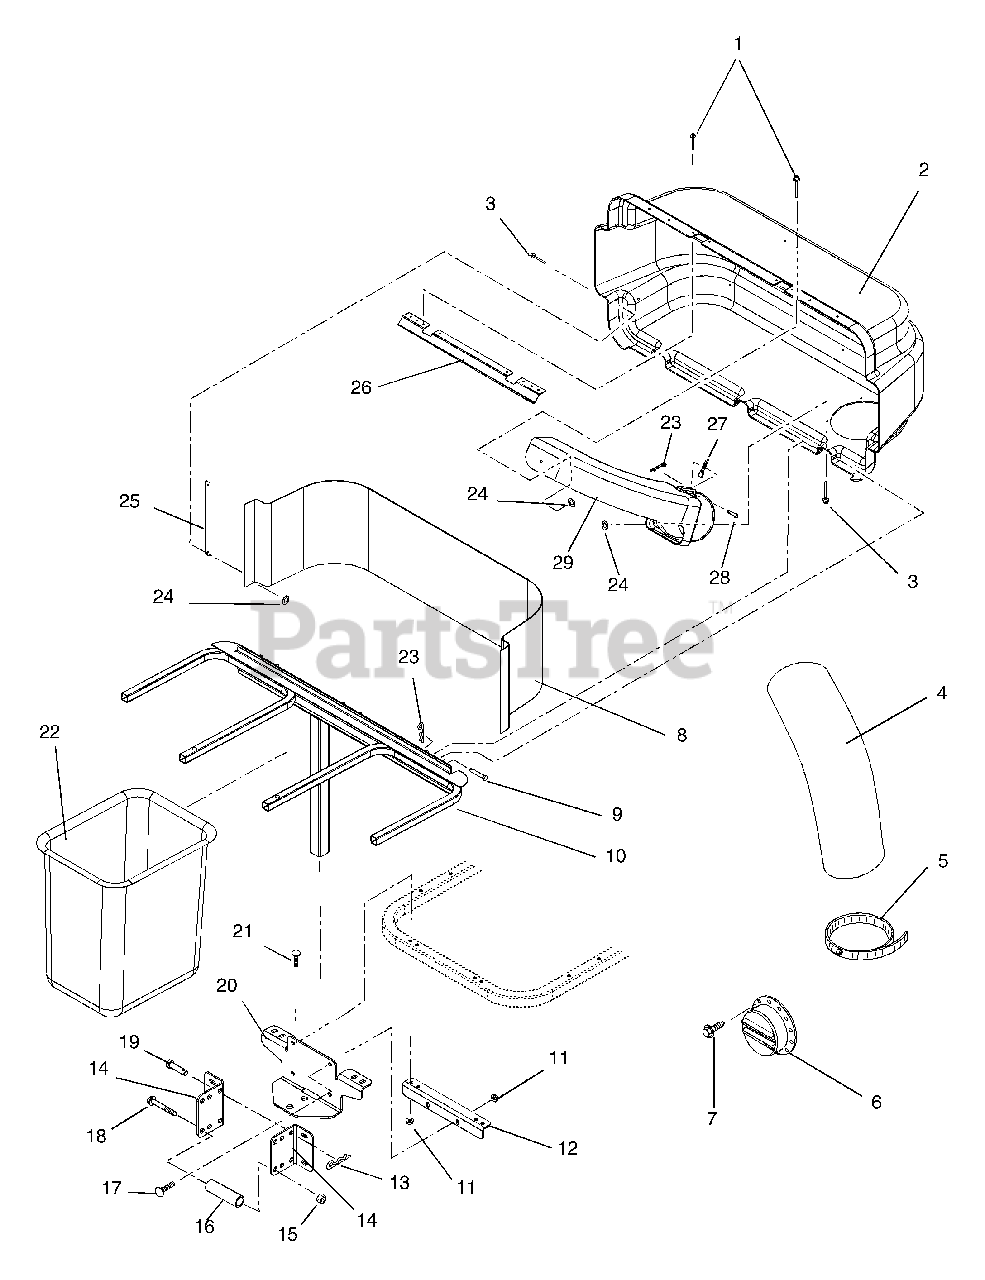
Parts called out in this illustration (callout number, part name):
1	RVT-POP .187X.402 DOME ST
2	BAGGER COVER W/DECAL
3	RVT-POP.187X.527 DOME ST
4	HOSE 7 X 45
5	CLAMP, 7" TOOL-LESS HOSE
6	DEFLECTOR,EXHAUST
7	SCR-TAP 8-32X.38 SL HWH YWZC
8	SCREEN, BAGGER
9	PIN-CLEV .371X3.25 YWZC
10	WMT,BAGGER FRAME
11	@NUT-LK-TOP-FLG .38-16 YWZC
12	BRKT,ANGLE
13	PIN-HAIR-EXT .12X.31X2.37 YWZC
14	BKT,BAGGER MOUNT
15	@NUT-LK-TOP-FLG .50-13 YWZC
16	SPACER, PIVOT .500X.750X1.805
17	@BLT-RDHDSQNK .38-16X1.25 G5YZ
18	@BLT-HEX .50-13X3.00 GR5 YWZC
19	PIN-CLEV .494X2.50 BRIGHT ZINC
20	TRAILER HITCH W/DECALS
21	@BLT-RDHDSQNK .38-16X2.50 G5YZ
22	GRASS BAGGER BASKET
23	PIN-HAIR, ENDRIES #25 YWZC
24	@WSHR-FL-STL.219X.50X.049 YWZC
25	STRAP,COVER
26	LATCH,COVER
27	INDICATOR, FLOW
28	PIN-CLEV .309 X 1.625 YWZC
29	BOOT,UPPER
